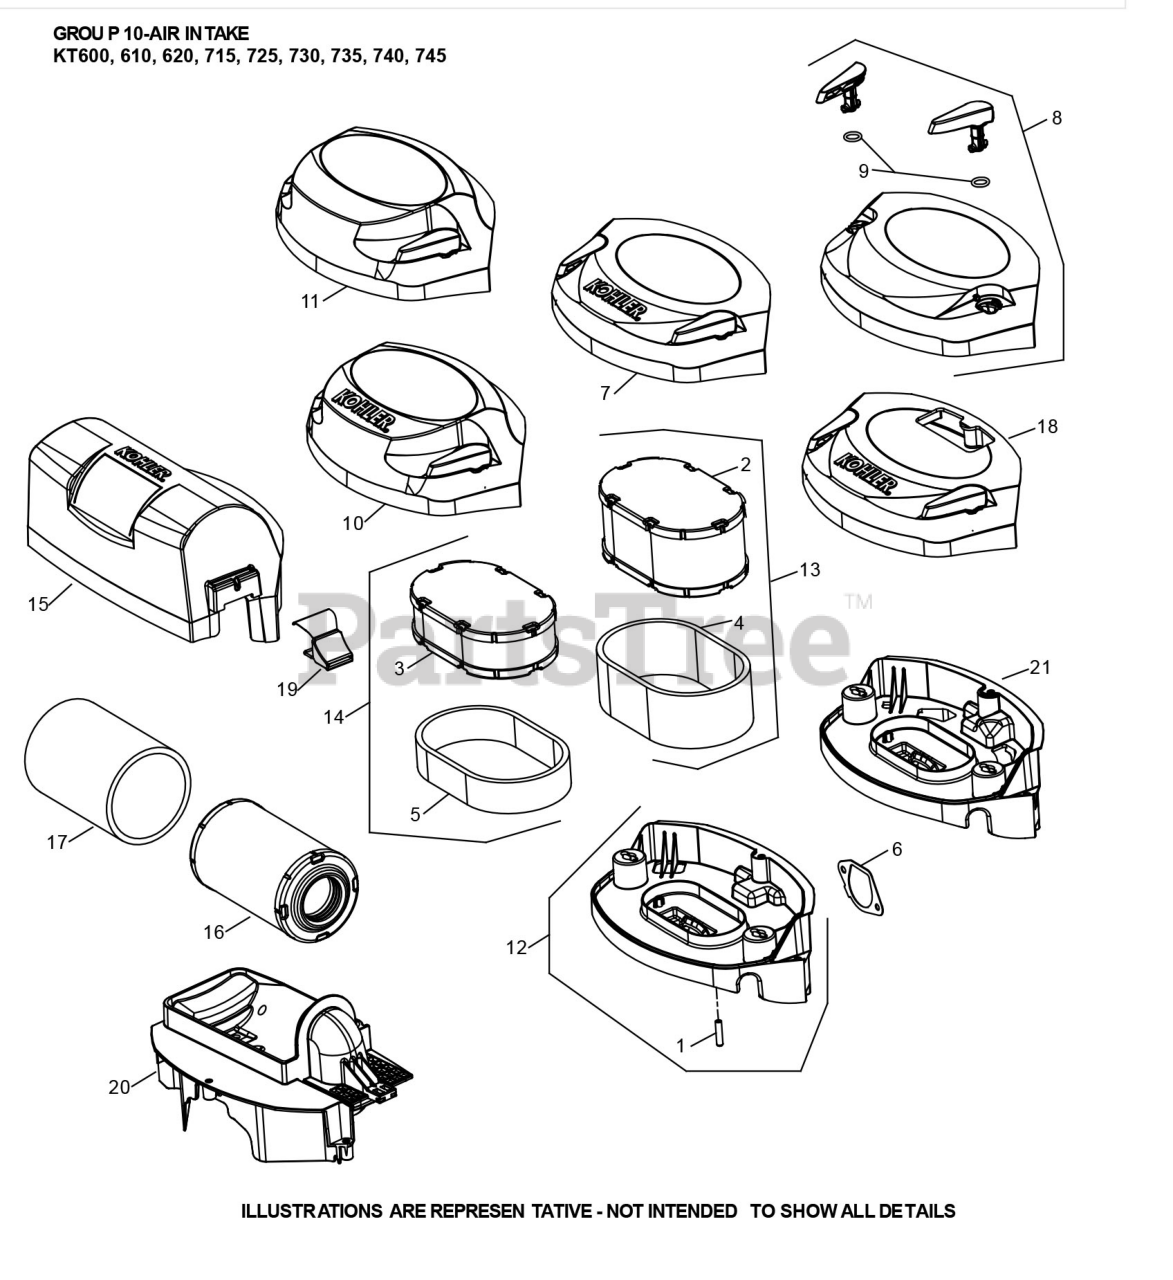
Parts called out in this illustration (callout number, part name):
2	FLTR KIT-AIR/PRECLNR (HPAC)
4	PRECLNR-FOAM (HPAC
6	GASKET-AIR CLNR BA
10	AIR CLEANER COVER ASSEMBLY
21	AIR CLEANER BASE ASSEMBLY
